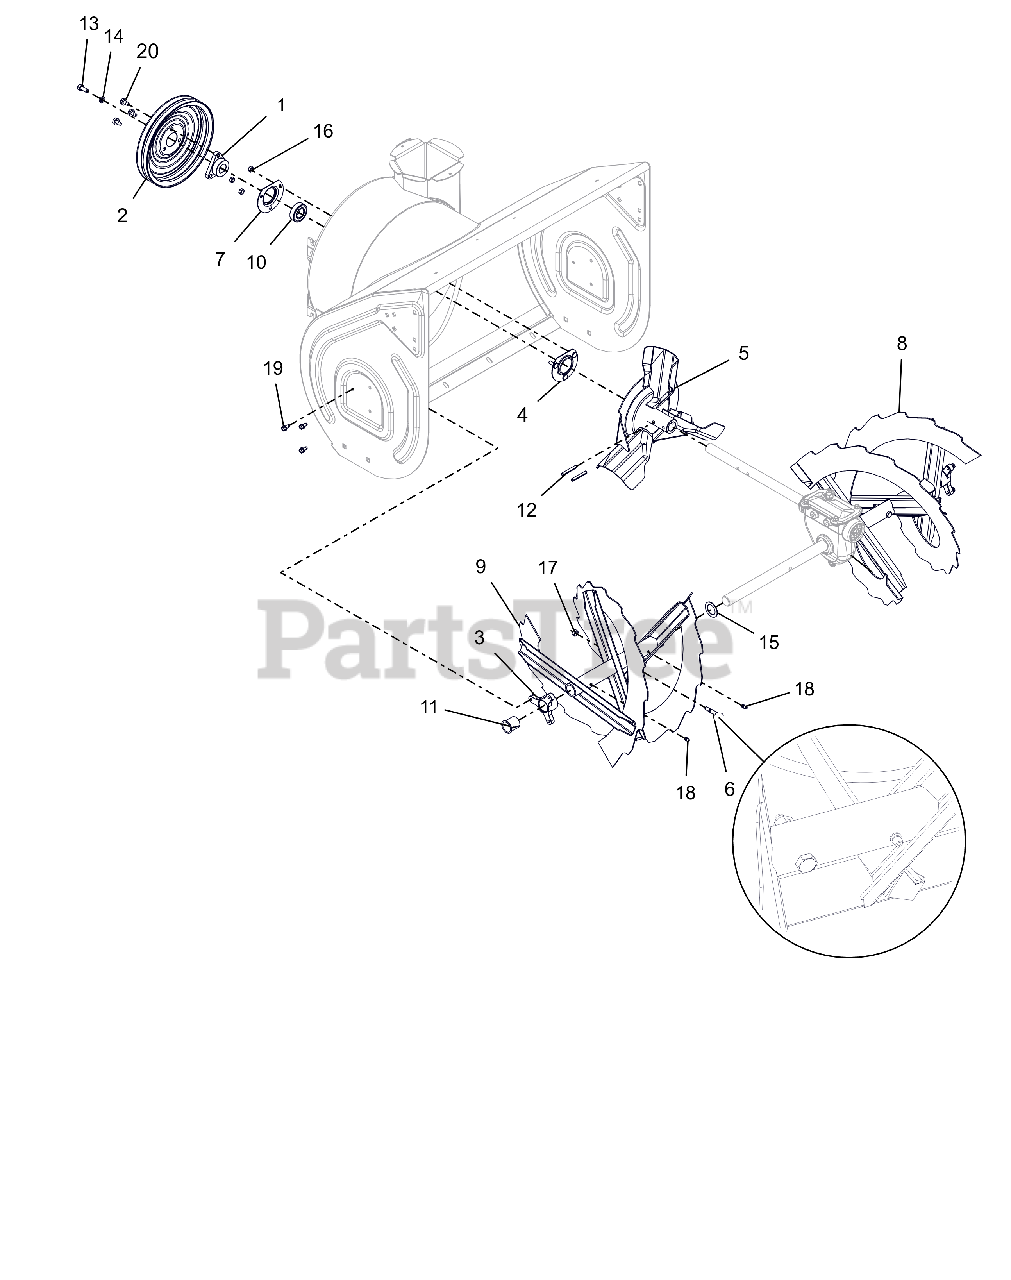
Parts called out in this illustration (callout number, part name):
1	PULLEY HUB, D-BORE .87 PRO
2	PULLEY, SPIN FORM DUAL GROOVE
3	BUSHING, RAKE SHAFT 1"
4	BEARING FLANGE
5	IMPELLER, 3 BLADE-14"
6	SHEAR BOLT SERVICE ASSEMBLY
7	BEARING FLANGE
8	RAKE, LH-28"(1 ID X 15.75 OD)
9	RAKE, RH-28"(1 ID X 15.75 OD)
10	BRG-BALL .876X1.75X.50 RSTFP
11	BSHG-FLG SPLIT NYLINER 1.0" HP
12	PIN-ROLL .250X1.75
13	BLT, HEX .31-24X.750 G5 ZCC
14	WSHR, LK-HVY .312X.097 ZCC
15	WSHR, FLT 1.010X1.505X.062 ZCC
16	NUT,LK-CTR .25-20 GA ZCC
17	NUT,LK-CTR .31-18 GA ZCC
18	ZERK,FITTING .25X.125 DRIVE IN
19	SCR-TAP .25-20X.50 HWH ZCC
20	SCR,TAP .312-18X.50 HWH TR ZCC
